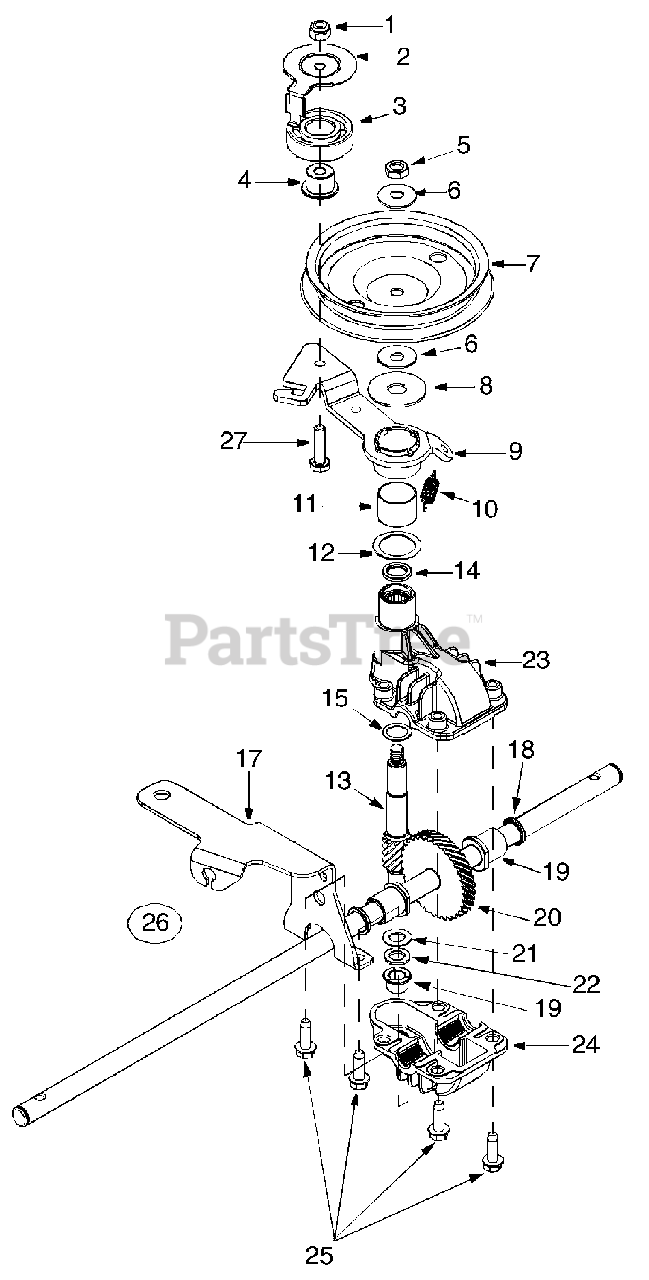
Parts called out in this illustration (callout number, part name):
2	Belt Keeper
3	Ball Bearing
4	Flange Bearing
5	Hex Jam Nut 5/16-24
6	Bell Washer .325 x .930 x .45
7	Pulley, 3.82 x .313 x .68
8	Flat Washer .422 x 1.38 x .060
9	Front Idler Assembly
10	Extension Spring
11	Bearing Sleeve
12	Fl-Wash. .865 x 1.145 x .030
13	Pinion Shaft
14	Needle Bearing .438 x .625 x .500
15	Flat Washer .504 x .700 x .030
17	Cable Idler Brkt.
18	Oil Seal
19	Flange Bearing
20	Output Shaft
21	Thrust Washer .375 x .070 x .030
22	Thrust Washer .388 x .625 x .062
23	Upper Housing
24	Lower Housing
25	Hex Screw w/Washer 1/4-20 x .750
26	Transmission Assembly Comp.
27	Hex Screw 1/4-28 x 1.0
